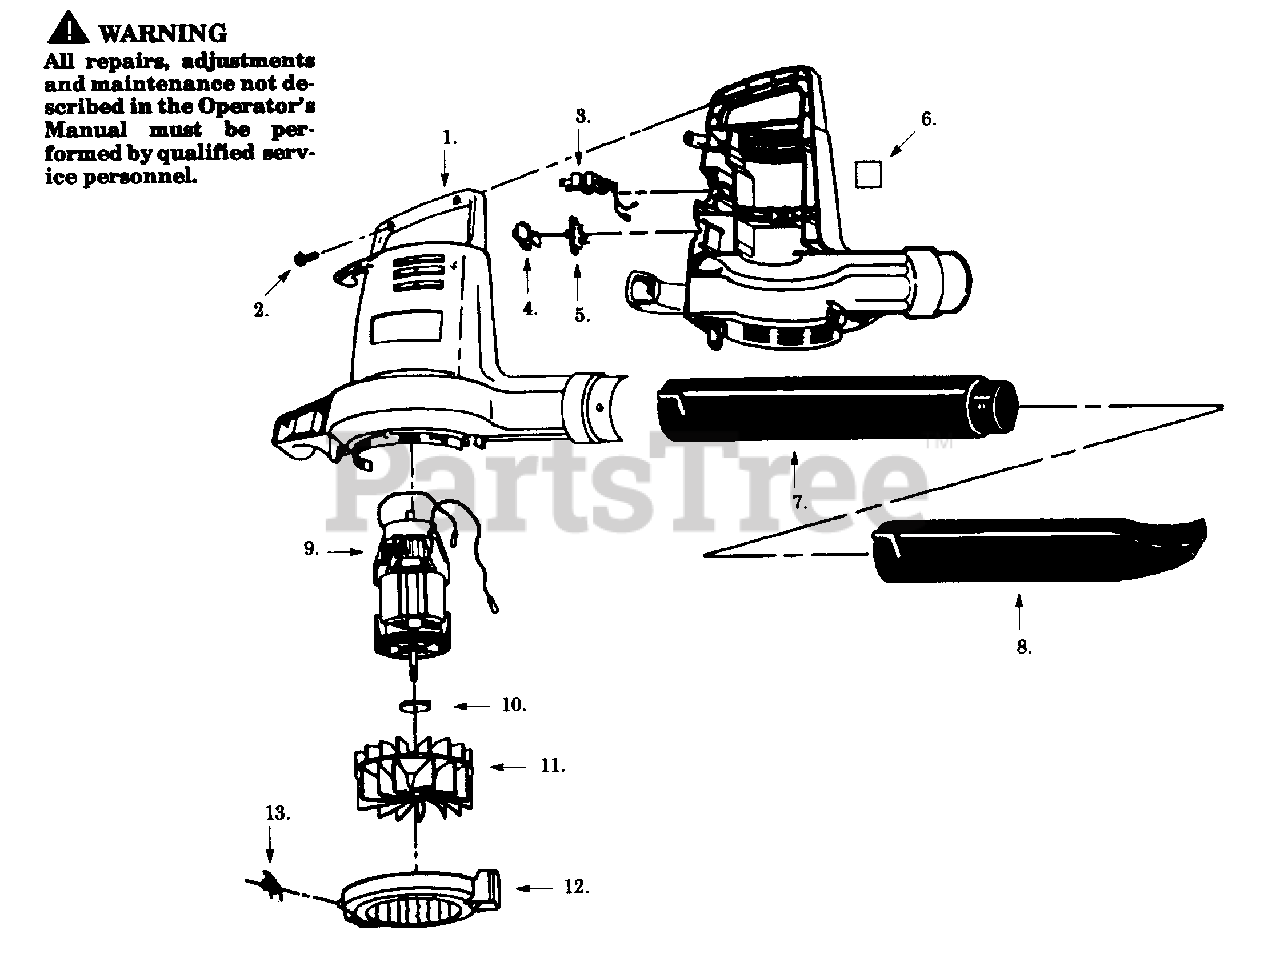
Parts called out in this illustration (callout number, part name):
1	Blower/Vac Hsg. Set
3	Wire Harness
4	Switch Cover
7	Blower Tube
9	Motor Ass'y.
11	Impeller
12	Inlet Cover
